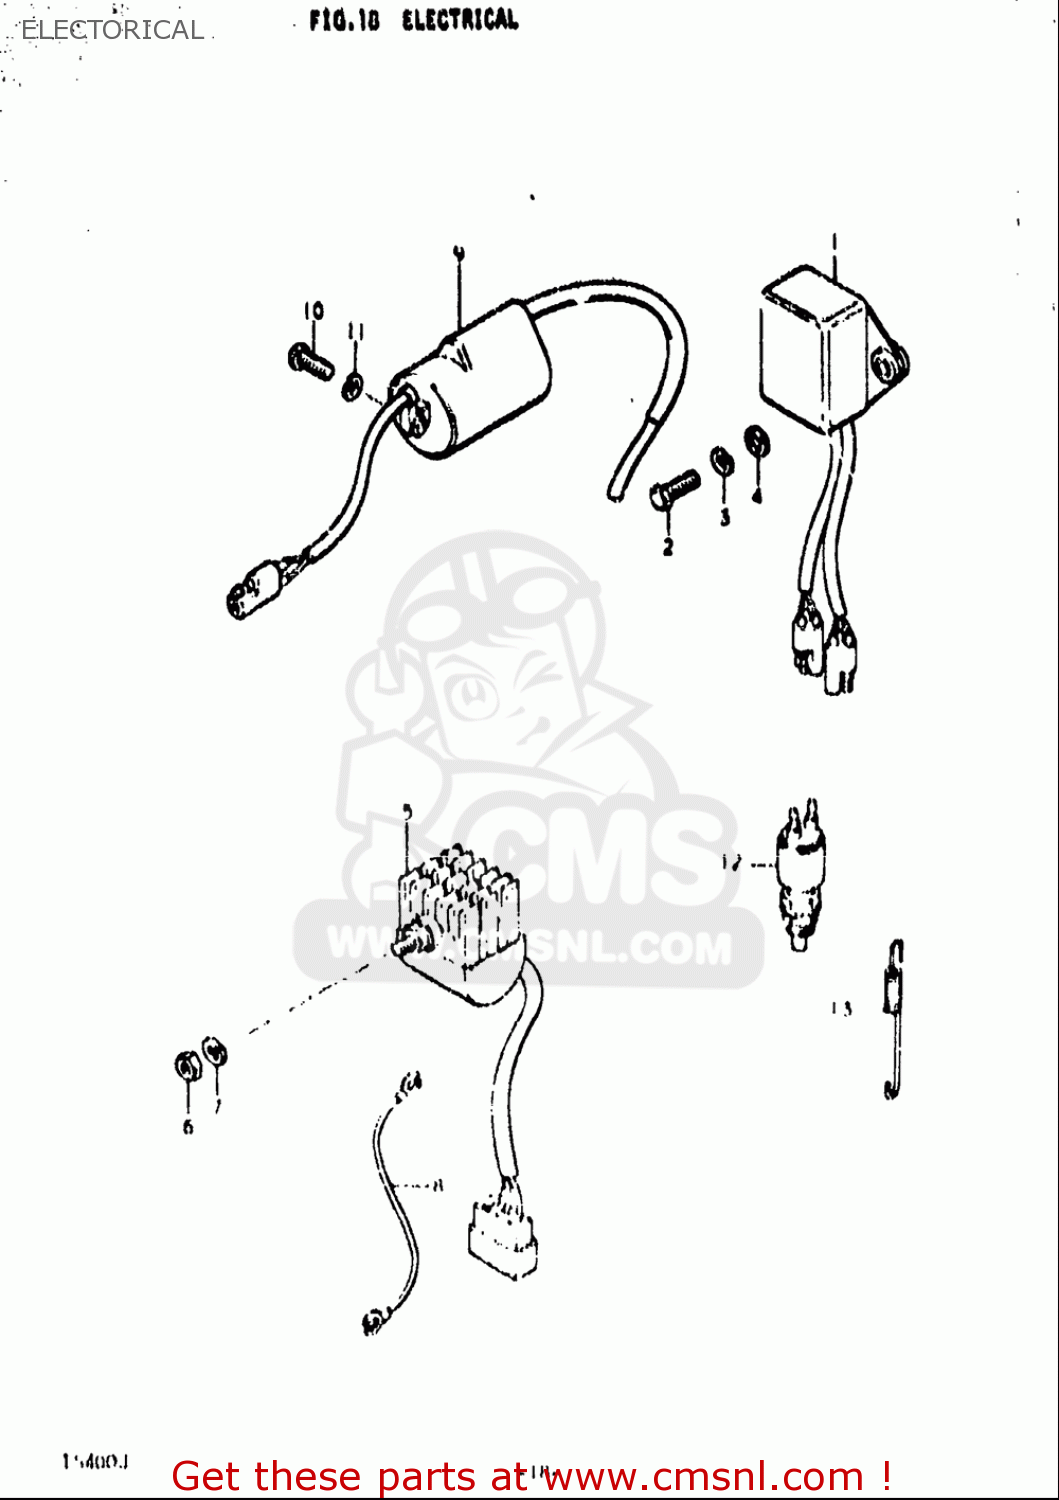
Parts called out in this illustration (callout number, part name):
2	BOLT(6X20)
3	WASHER,LOCK
4	WASHER
5	RECTIFIER ASSY
6	NUT
7	WASHER,LOCK
8	LEAD WIRE,EARTH
9	COIL ASSY,IGNITION
10	SCREW
11	WASHER,LOCK
12	SWITCH ASSY,BRAKE LAMP
13	SPRING
